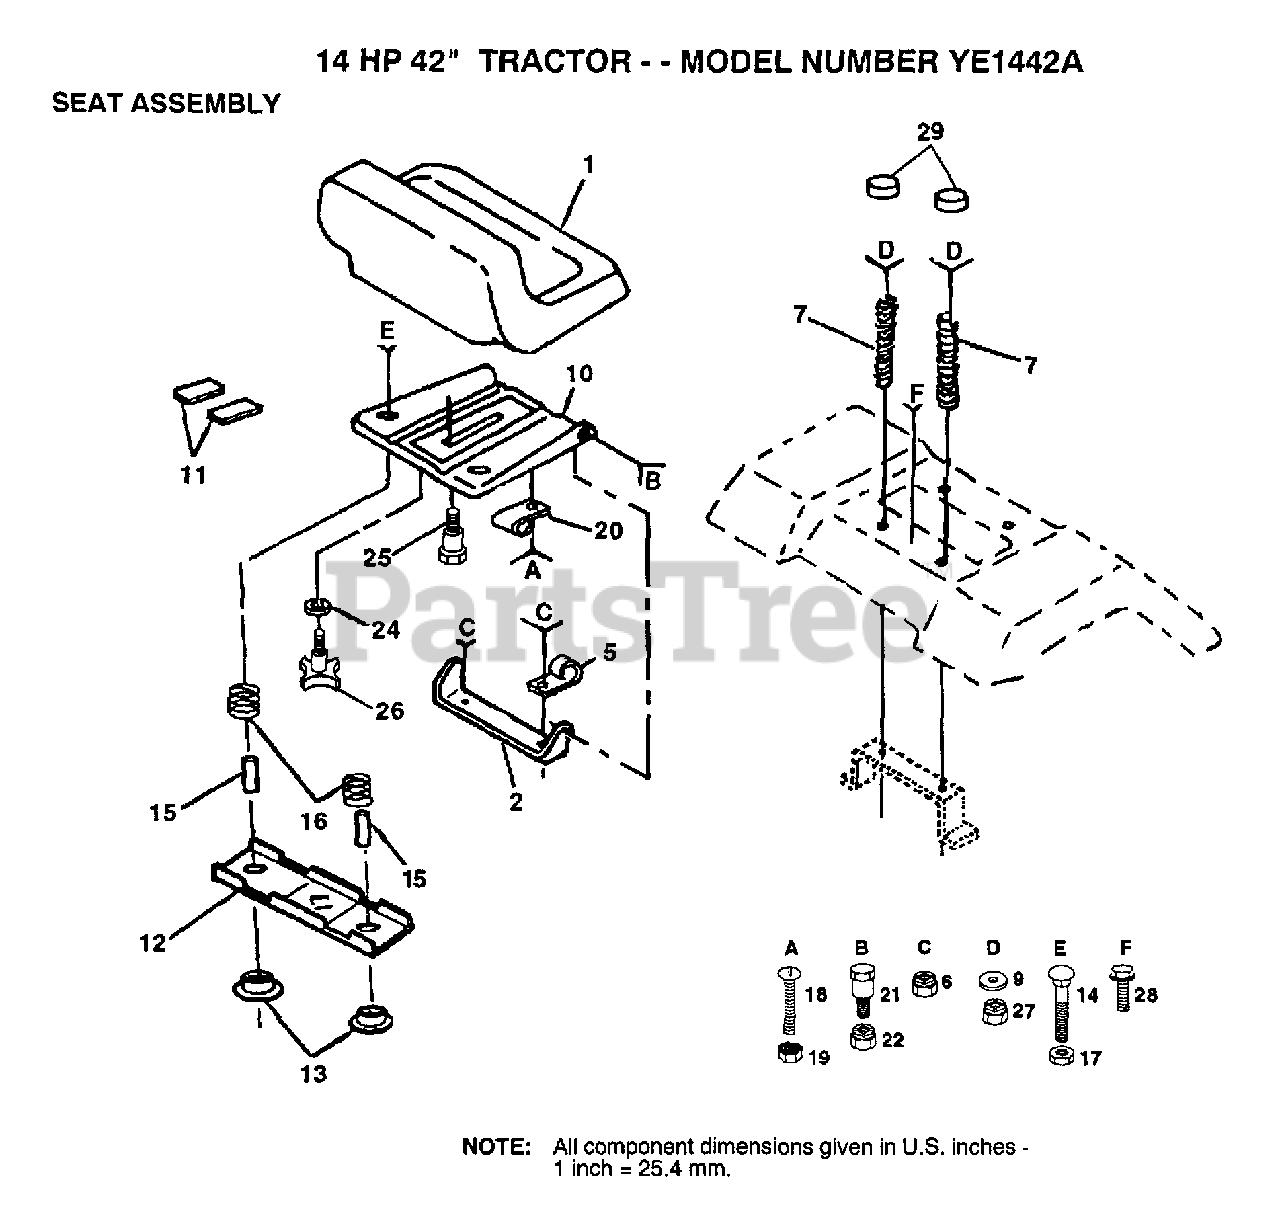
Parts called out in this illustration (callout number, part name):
5	CLIP T
7	SPRING COMPRESSIO
9	WASHER
11	STRIP FORM
12	BRKT SWITCH
13	BUSHING
15	SPLIT SPACER
16	SPRING
19	"NUT,KEPS"
24	WASHER
25	"BOLT,SHOULDER"
26	"KNOB 1/2"" YT"
28	SCREW
29	CAP SPRING
